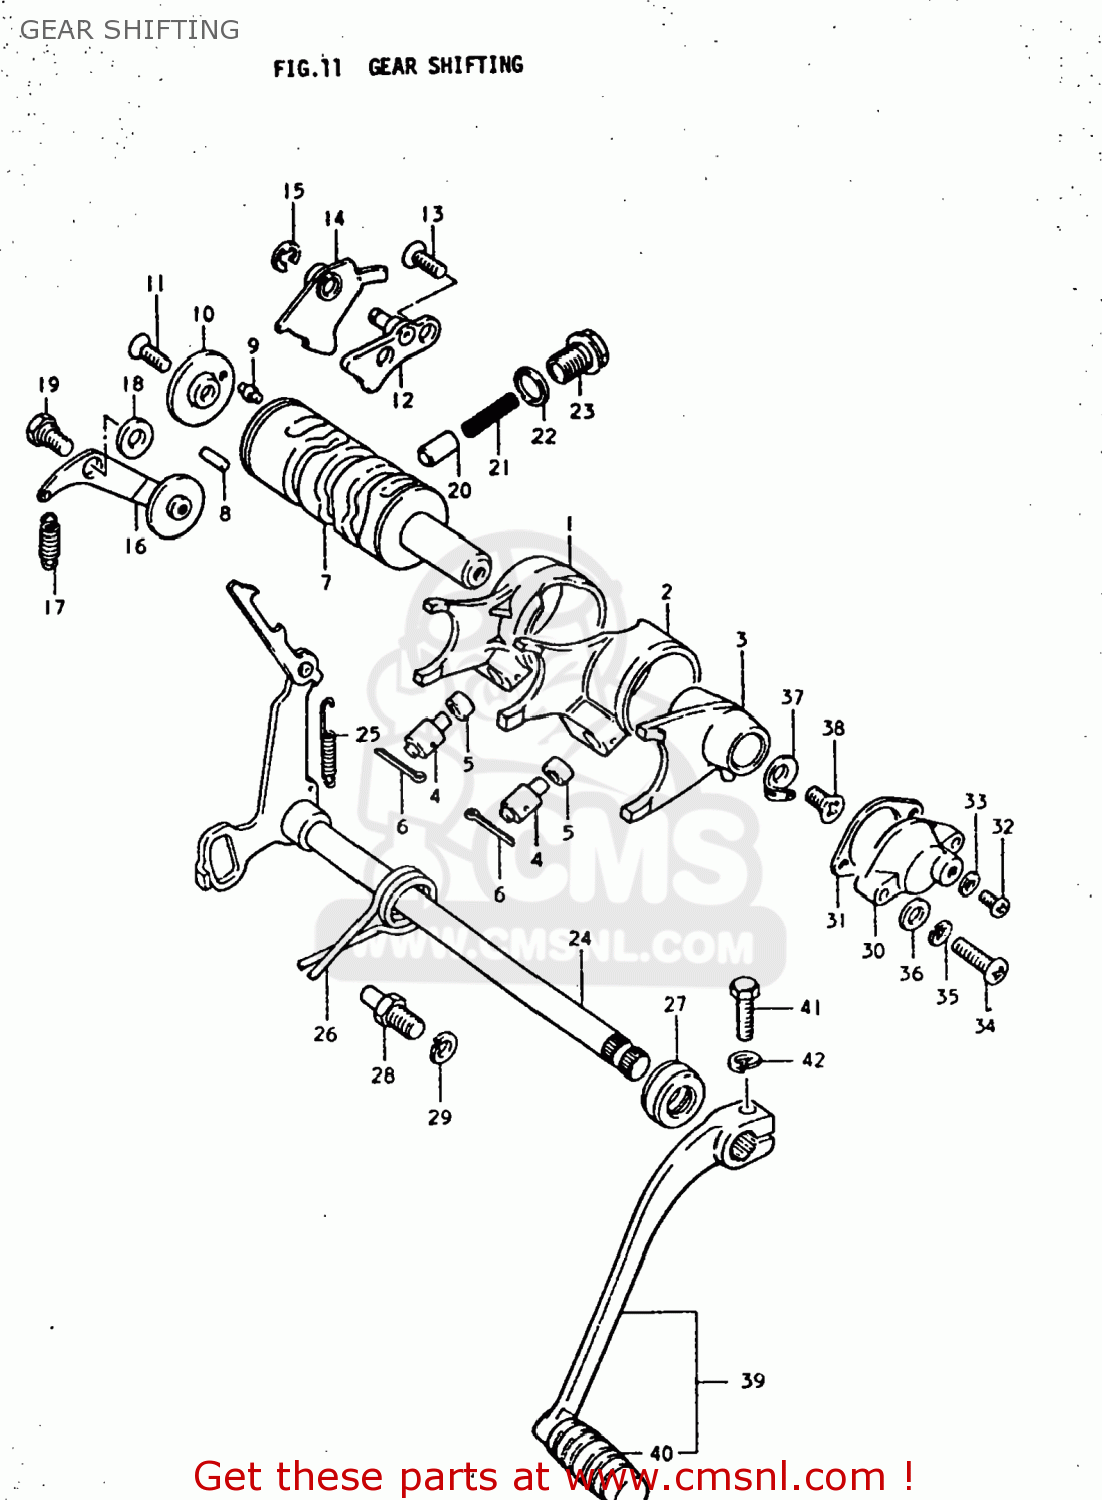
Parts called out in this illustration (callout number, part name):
1	FORK,GEAR SHIFT NO.1
2	FORK,GEAR SHIFT NO.2
3	FORK, REDUCTION GEAR.
4	PIN
5	SPACER
6	PIN 25X20
7	CAM,GEAR SHIFT
8	ROLLER(4X13.8)
9	PIN
10	RETAINER,GEAR SHIFT CAM DR PIN
11	SCREW
12	GUIDE,GEAR SHIFT CAM
13	SCREW
14	PAWL,GEAR SHIFTING CAM
15	E RING
16	STOPPER,GEAR SHIFT CAM
17	SPRING
18	WASHER(6.5X16X2.3)
19	BOLT(6X16.1)
20	STOPPER,GEAR SHIFTING
21	SPRING
22	GASKET(14X19.2X2) (NAS)
23	BOLT,GEAR SHAFT CAM STOPPER
24	SHAFT,GEAR SHIFT
25	SPRING
26	SPRING
27	OIL SEAL
28	STOPPER,GEAR SHIFT ARM
29	LOCK WASHER
30	BODY,GEAR SHIFT SWITCH
31	32
32	SCREW
33	WASHER
34	SCREW
35	LOCK WASHER
36	WASHER
37	CONTACT,GEAR SHIFT SWITCH
38	SCREW
39	LEVER ASSEMBLY,GEAR SHIFTING
40	RUBBER,GEAR SHIFT PEDAL
41	BOLT
42	LOCK WASHER
